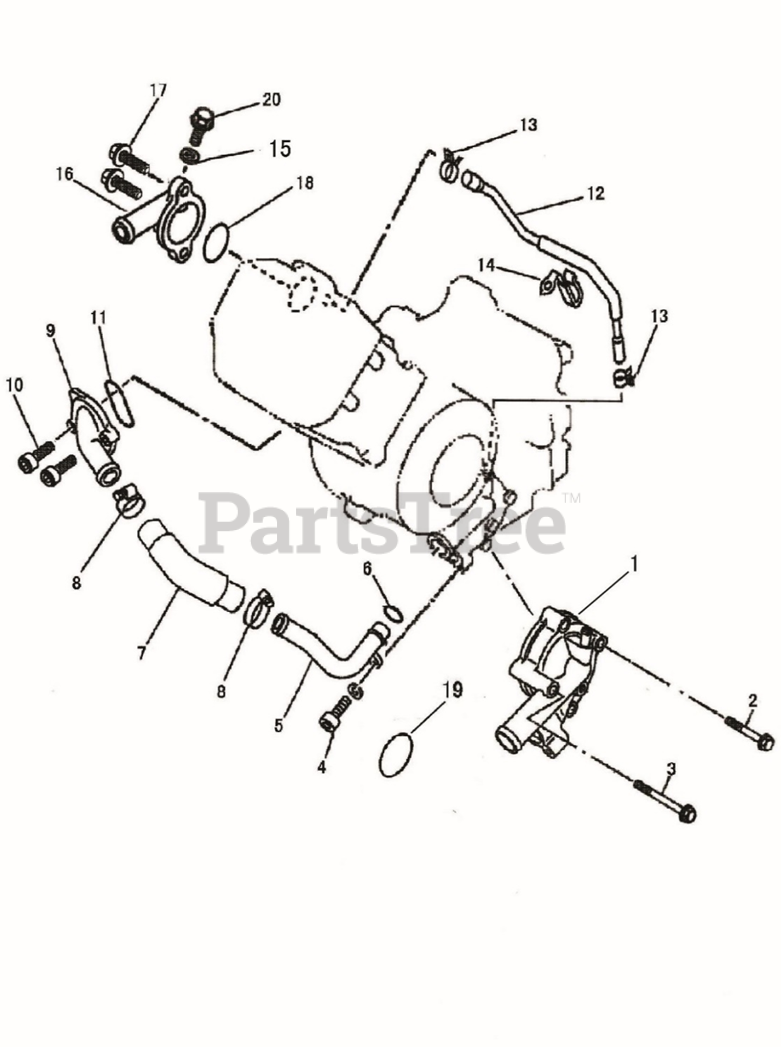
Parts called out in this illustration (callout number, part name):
1	WATER PUMP ASSEMBLY
2	HEX FLANGE BOLT M6X45
3	HEX FLANGE BOLT M6X65
4	HEX FLANGE BOLTS M6X16
5	WATER PIPE (CHALLENGER 750)
6	O-RING 20.7X2.6
7	HOSE (CHALLENGER 750)
8	HOSE CLAMP ASSEMBLY
9	OUTLET WATER HOSE
10	HEX FLANGE BOLTS M6X20
11	O-RING 33.4X2.4
12	WATER PIPE I
14	PIPE CLAMP
15	ALUMINUM WASHER 6X12X1.5
16	THERMOSTAT COVER
17	HEX FLANGE BOLTS M6X20
18	THERMOSTAT COVER SEAL
19	O-RING 34.2X2.5
20	HEX FLANGE BOLT M6X12
